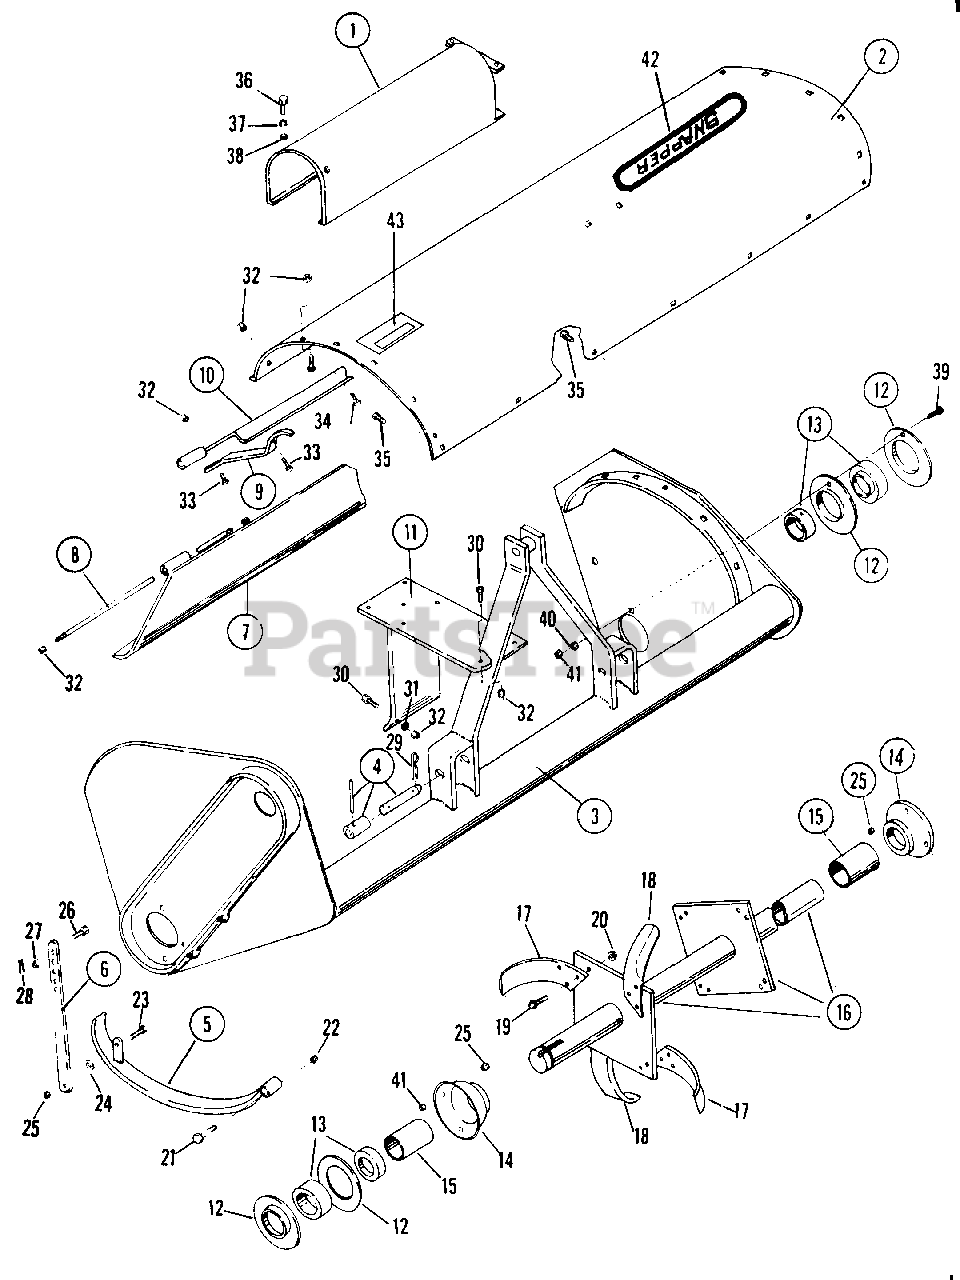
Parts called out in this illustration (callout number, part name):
1	SHIELD, TORQUE LIMITER TUNNEL
2	SHROUD, TILLER
4	PIN ASSEMBLY
6	STRAP, ADJUSTING
7	LEVEL - BLADE
8	ROD, HINGE
9	STRAP, SUPPORT
10	BRACKET, HINGE
11	MOUNT, GEAR BOX
12	FLANGETTE, 4-HOLE
13	BEARING, SEALED WITH LOCK COLLAR 1-1/2"
14	CAP, BEARING GUARD (DUST)
15	TUBE, TINE SHAFT LOCK
16	SHAFT, TINE
17	TINE, SINGLE RIGHT HAND
18	TINE, SINGLE LEFT HAND
19	BOLT, HEX FLANGED HEAD
20	LOCKNUT, HEX FLANGED
21	BOLT, 5/8-11 x 2-3/4 HEX - GRADE 5
22	NUT, 5/8-11 HEX
23	BOLT, 1/2-13 x 1-1/2 HEX - GRADE 2
24	WASHER, RUBBER
25	LOCKNUT, 1/2-13 HEX
26	BOLT, SPECIAL HEX (Make from 7092108 - machine & drill)
27	WASHER, 1/2" PLAIN
28	PIN, COTTER HAIR 1/8 x 1-7/8
29	HAIR PIN, .0148 X 2.62 YZ
30	BOLT, 3/8-16 x 1" HEX - GRADE 5
31	WASHER, 3/8 PLAIN
32	LOC K NUT, 3/8-16 HEX
33	BOLT, 3/8-16 x 1" CARRIAGE
34	BOLT, 3/8-16 x 3/4 CARRIAGE
35	SCREW, 5/16-18 x 3/4 SELF-TAPPING
36	SCREW, 5/16-18 x 1/2 HEX HEAD
37	LOCKWASHER, 5/16
38	WASHER, 5/16 SAE PLAIN
39	BOLT, Carriage 1/2-13X1-3/4 GR5
40	NUT, 1/2-13 HEX
41	SPACER, BEARING CAP
42	DECAL, SNAPPER
43	DECAL, CAUTION
